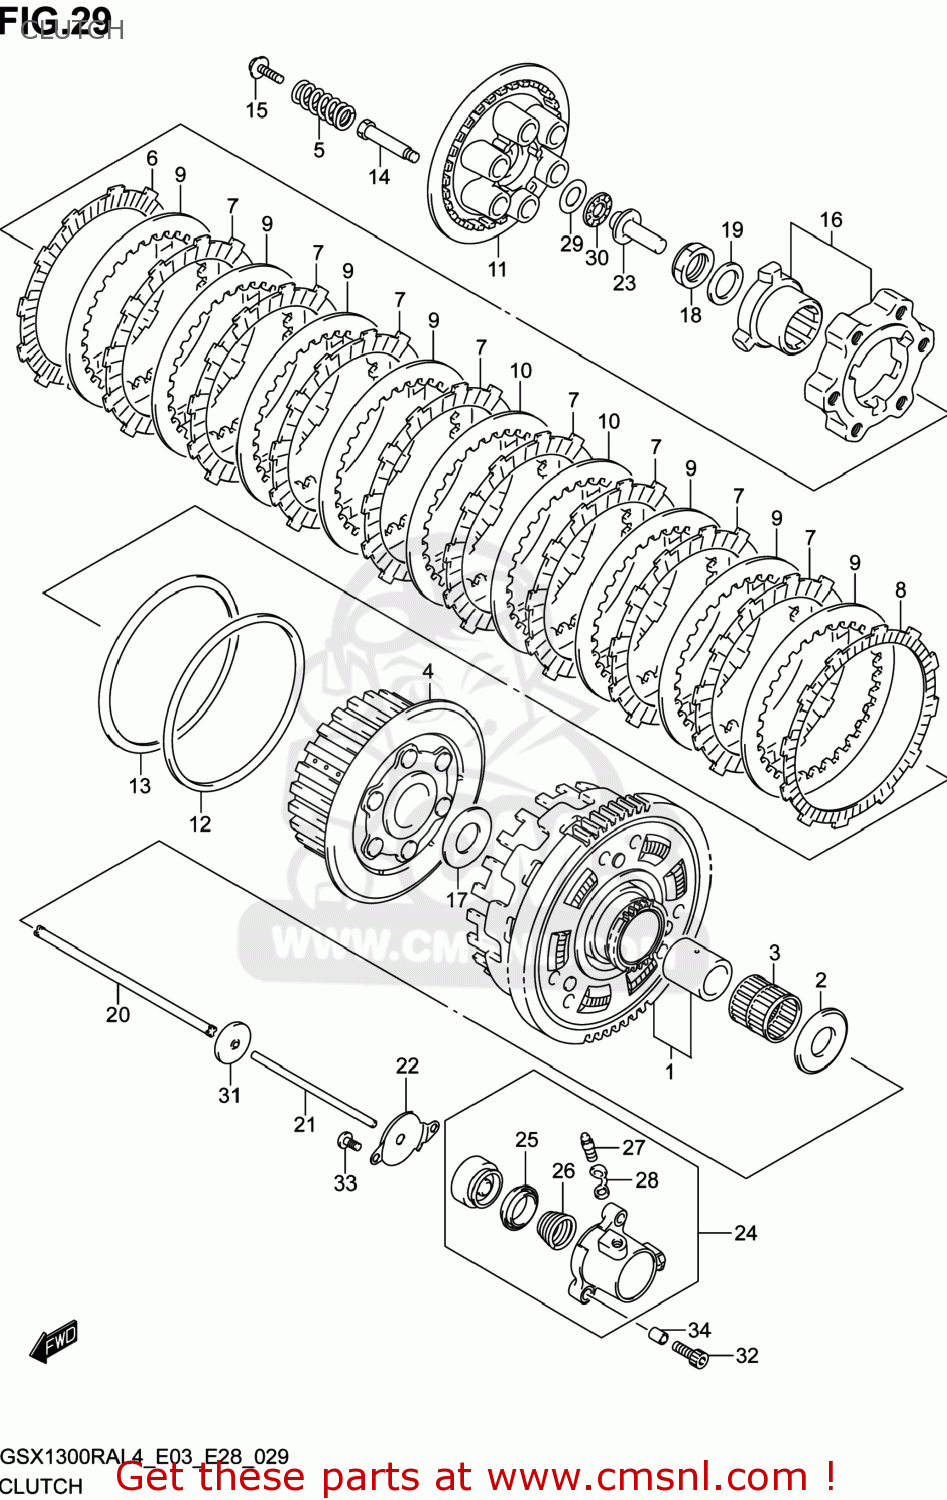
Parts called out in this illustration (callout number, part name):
1	GEAR ASSY,PRI DRIVEN
2	WASHER(25X54X2.4)
3	BEARING(35X40X39.8)
4	HUB,CLUTCH SLEEVE
5	SPRING,CLUTCH
6	PLATE,CLUTCH DRIVE NO.2 (NAS)
7	PLATE,CLUTCH DRIVE NO.1 (NAS)
8	PLATE,CLUTCH DRIVE NO.3 (NAS)
9	PLATE,CLUTCH DRIVEN NO.1(T:2.0 (NAS)
10	PLATE,CLUTCH DRIVEN NO.2(T:2.3 (NAS)
11	DISC,CLUTCH PRESSURE
12	SEAT,WAVE WASHER
13	WASHER,CLUTCH PLATE WAVE
14	BOLT,CLUTCH SPRING SUPPORT
15	BOLT,CLUTCH SPRING
16	CAM SET,CLUTCH
17	WASHER(25X50X2.5)
18	NUT
19	WASHER
20	ROD,CLUTCH
21	ROD,CLUTCH PUSH,L
22	COVER,CLUTCH RELEASE CYLINDER
23	PIECE,CLUTCH PUSH
24	CYLINDER,CLUTCH RELEASE
25	CUP
26	SPRING
27	BLEEDER
28	CAP,BLEEDER
29	WASHER(15.5X28X1)
30	BEARING(15X28X2)
31	SEAL,OIL(6X34X5.5)
32	BOLT
33	SCREW
34	PIN
